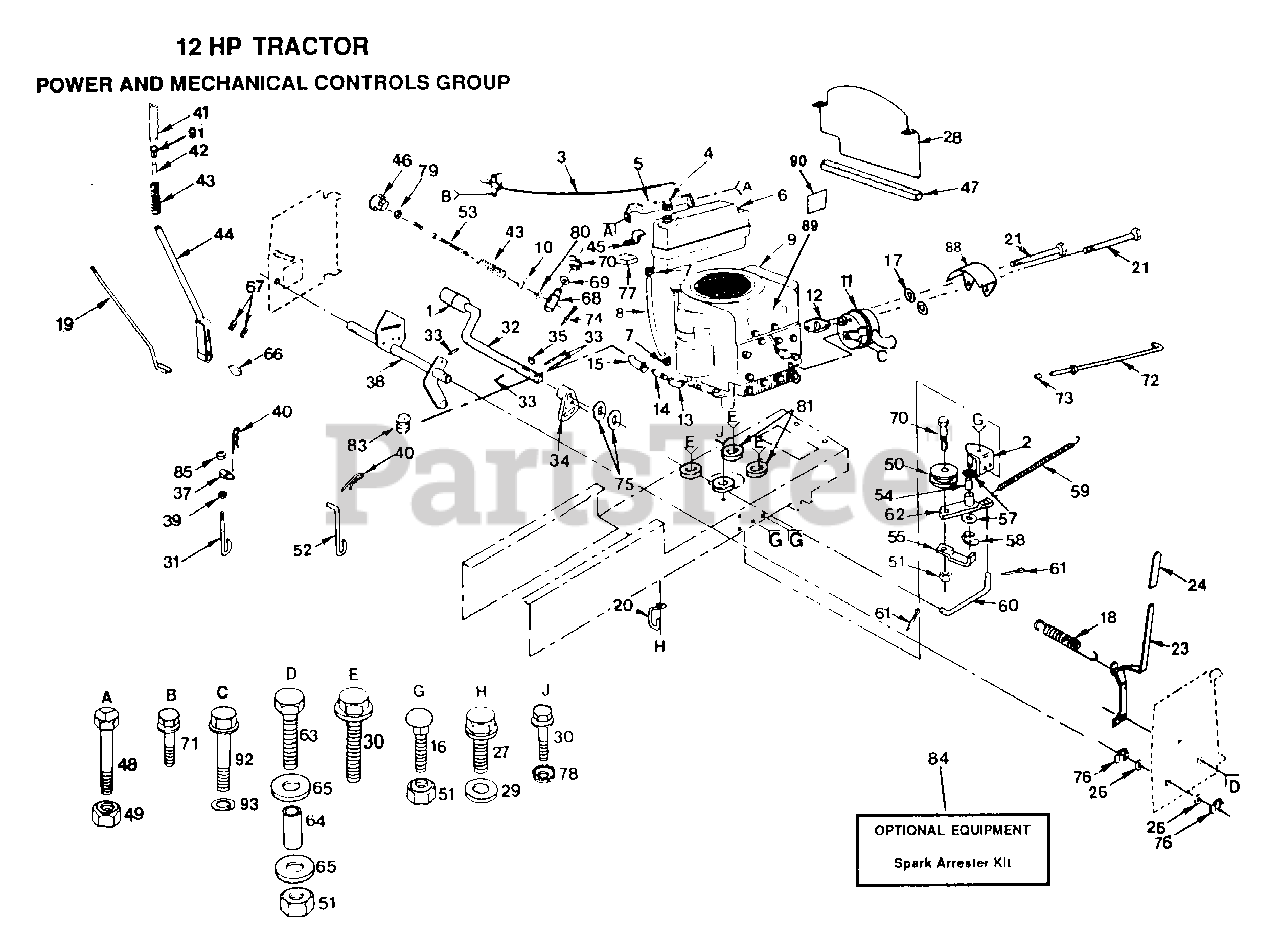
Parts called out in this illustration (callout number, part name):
5	SUPT TANK FUEL
6	FUEL TANK
8	HOSE T
9	ENGINE 12 H.P. TYPE 0201-01
10	WASHER
11	MUFFLER
13	STREET ELBOW LT
14	PIPE NIPPLE
15	ELBOW
16	BOLT
17	LOCKWASHER
18	"SPRING.EXT.8.5"""
19	ROD ASS'Y LEVER
21	SCREW LT
26	WASHER
27	SCREW
29	WASHER
30	SCREW LT
31	PIVOT PIN T
32	FOOT SHAFT PEDAL
34	ARM BRAKE LT
39	NUT
41	GRIP
43	SPRING T
45	BRACE-TANK LT
46	HDLE ADJ LIFT
48	BOLT
52	LIFT LINK LT
53	ROD LIFT LT
54	"LY, BEARING"
57	WASHER LT
58	KLIP RING
59	"SPRING, RETURN LT"
60	"LINK, CLUTCH T"
61	COTTER PIN
68	TRUNION LT
69	WASHER
70	KLIP RING
71	SCREW
73	PLUNGER CAP T
75	WASHER
76	E-RING
77	PAD-SPACER T
78	LOCKWASHER
79	NUT
80	NUT T
83	PLUG T
84	SPARK ARREST KIT
86	SCREW
87	WASHER M
88	HEAT SHIELD
89	DECAL.ENG.271967
92	BOLT
93	LOCKWASHER
